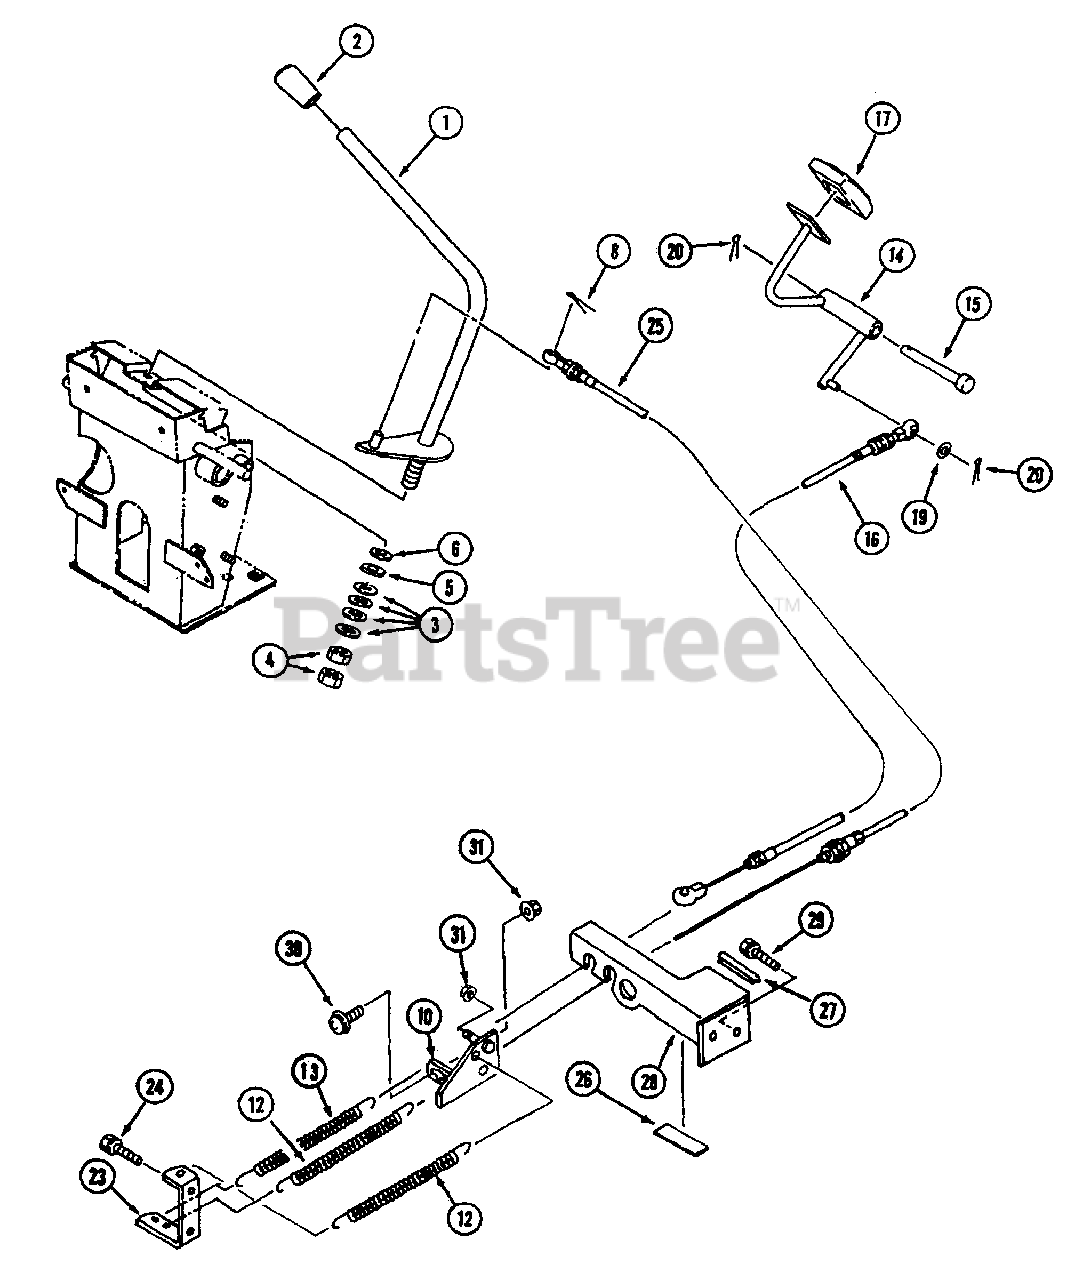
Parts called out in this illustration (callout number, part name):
1	Lever, Accelerator
5	Lining, Brake
6	Liner
8	Pin Split
13	Spring (Gear Only)
14	Pedal, Accelerator (Gear Only)
15	Pin (Gear Only)
16	Wire, Accelerator F (Gear Only)
17	Cover Pedal (Gear Only)
19	Washer (Gear Only)
20	Pin Split (Gear Only)
25	Wire, Accelerator H
